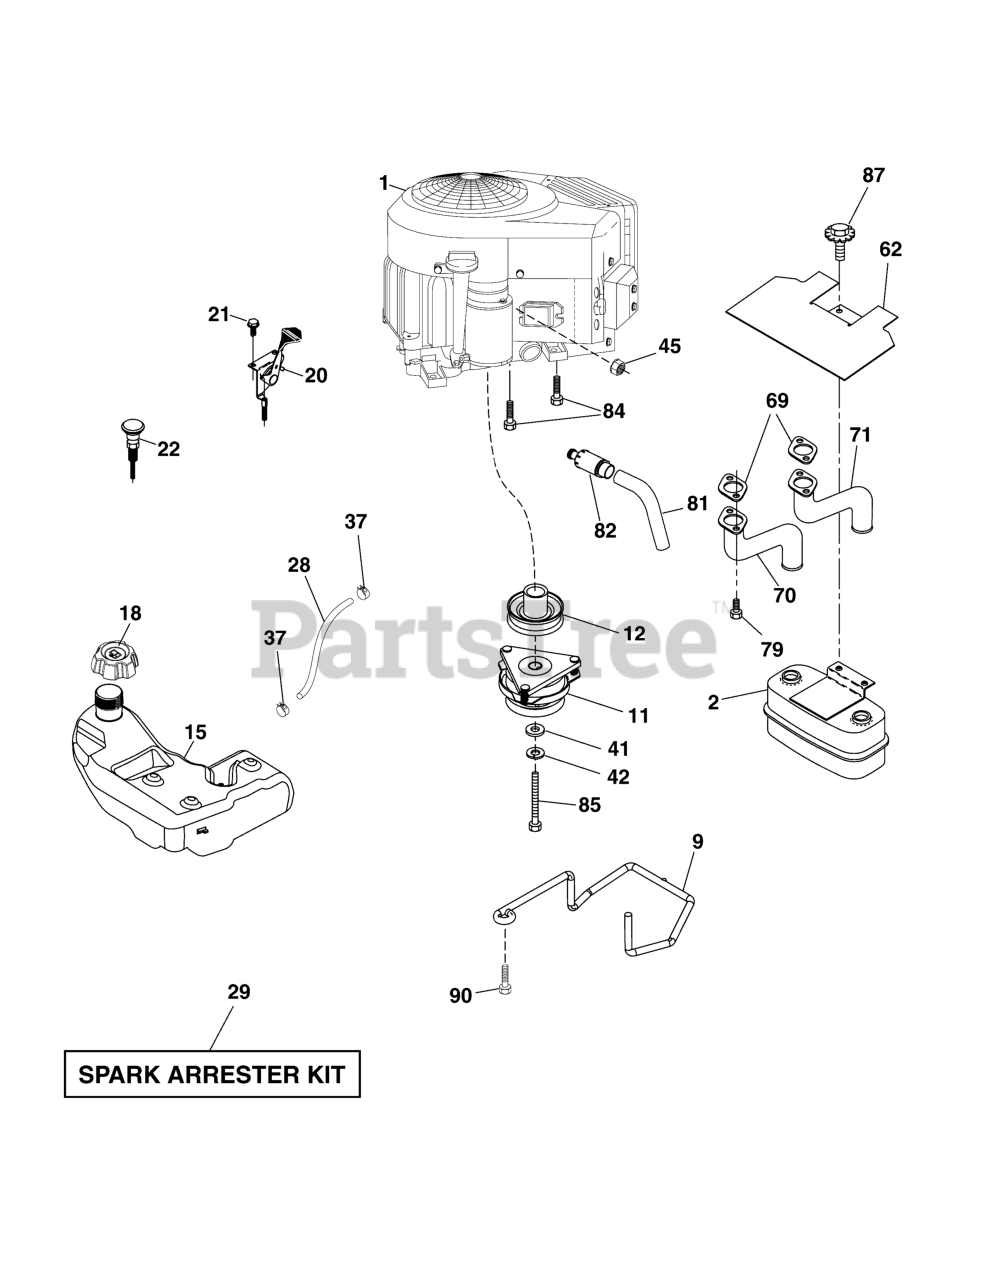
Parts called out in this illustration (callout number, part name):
1	ENGINE, 26HP Briggs & Stratton
2	Muffler
9	Keeper Asm. Belt Engine
11	Clutch Electric
12	Pulley Engine
15	Tank Fuel 4.0
18	Cap Asm
20	Control
21	Screw 10 x .750 BOS Thread
22	Control Choke
28	Fuel Line
29	Spark Arrester Kit
37	Clamp Hose
41	Washer 1-1/2 OD x 15/32 ID x .250
42	Washer Lock 7/16
45	Nut Keps 1/4-20 unc
62	Shield Heat Muffler
69	Gasket
70	Tube Exhaust LH
71	Tube Exhaust RH
79	Screw Socket Head 5/16-18 x 1
81	Tube Drain Oil Easy
82	Valve Oil Drain
84	Screw 3/8-16 x 1-1/4
85	Bolt Hex 7/16-20 x 3.75 Gr. 5
87	Bolt 5/16-18 unc x 1 w/Sems
90	Screw 3/8-16 x 1
